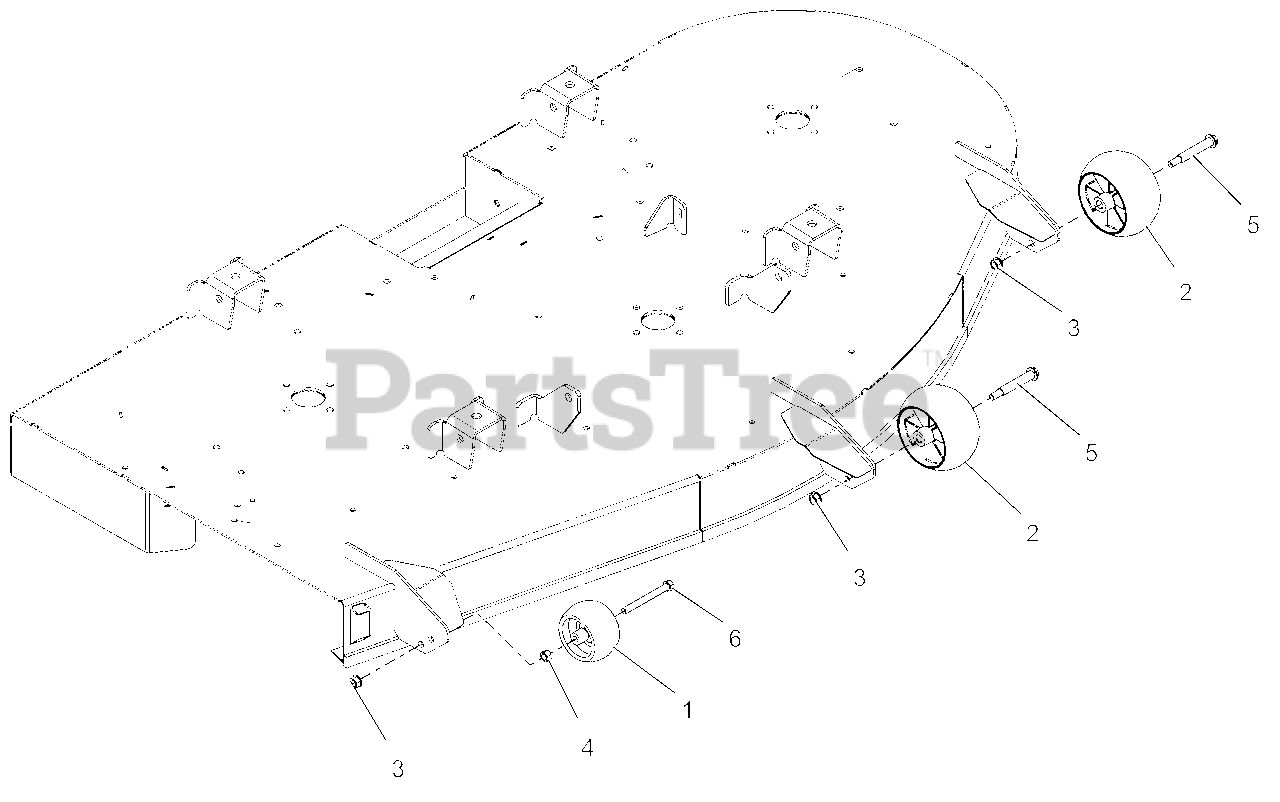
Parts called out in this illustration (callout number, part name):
2	ANTI-SCALP WHEEL - 5X OS
3	NUT-LK-CTR-FLG .375-16 GF ZCC
4	NUT-STD .375-16 G2 ZCC
5	BLT-SHLDR .38-16X2.50 HWH G5
6	BLT, HEX .38-16X3.50 G5 ZCC
